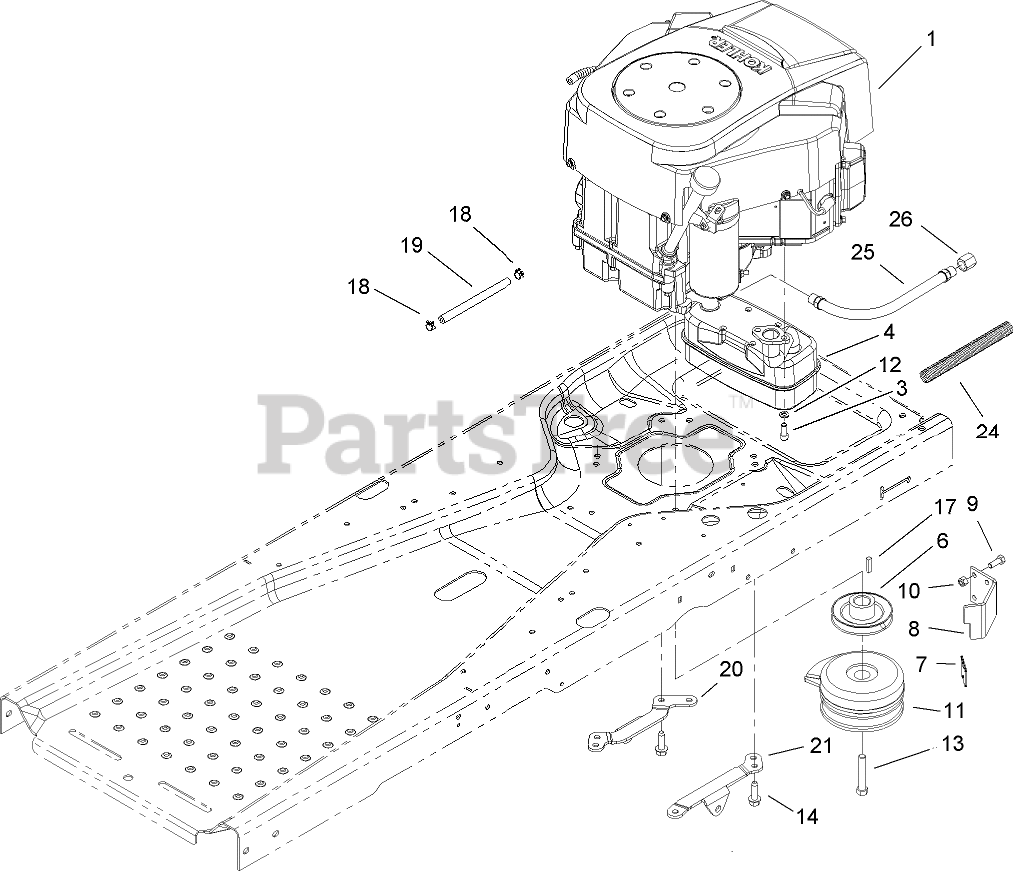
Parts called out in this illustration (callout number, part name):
3	SCREW-HSH
4	MUFFLER
6	PULLEY-ENGINE
7	BUMPER
8	STOP-CLUTCH
9	SCREW-HH
10	NUT-LOCK, NI
11	CLUTCH-ELECTRIC, PTO
12	WASHER-LOCK
13	SCREW-HH
14	SCREW-TAPTITE
18	CLAMP-HOSE
19	HOSE-FUEL
20	SUPPORT-HYDRO, RH
21	SUPPORT-HYDRO, LH
24	TUBING-CONVOLUTED
25	HYD HOSE ASM
26	CAP-PIPE
